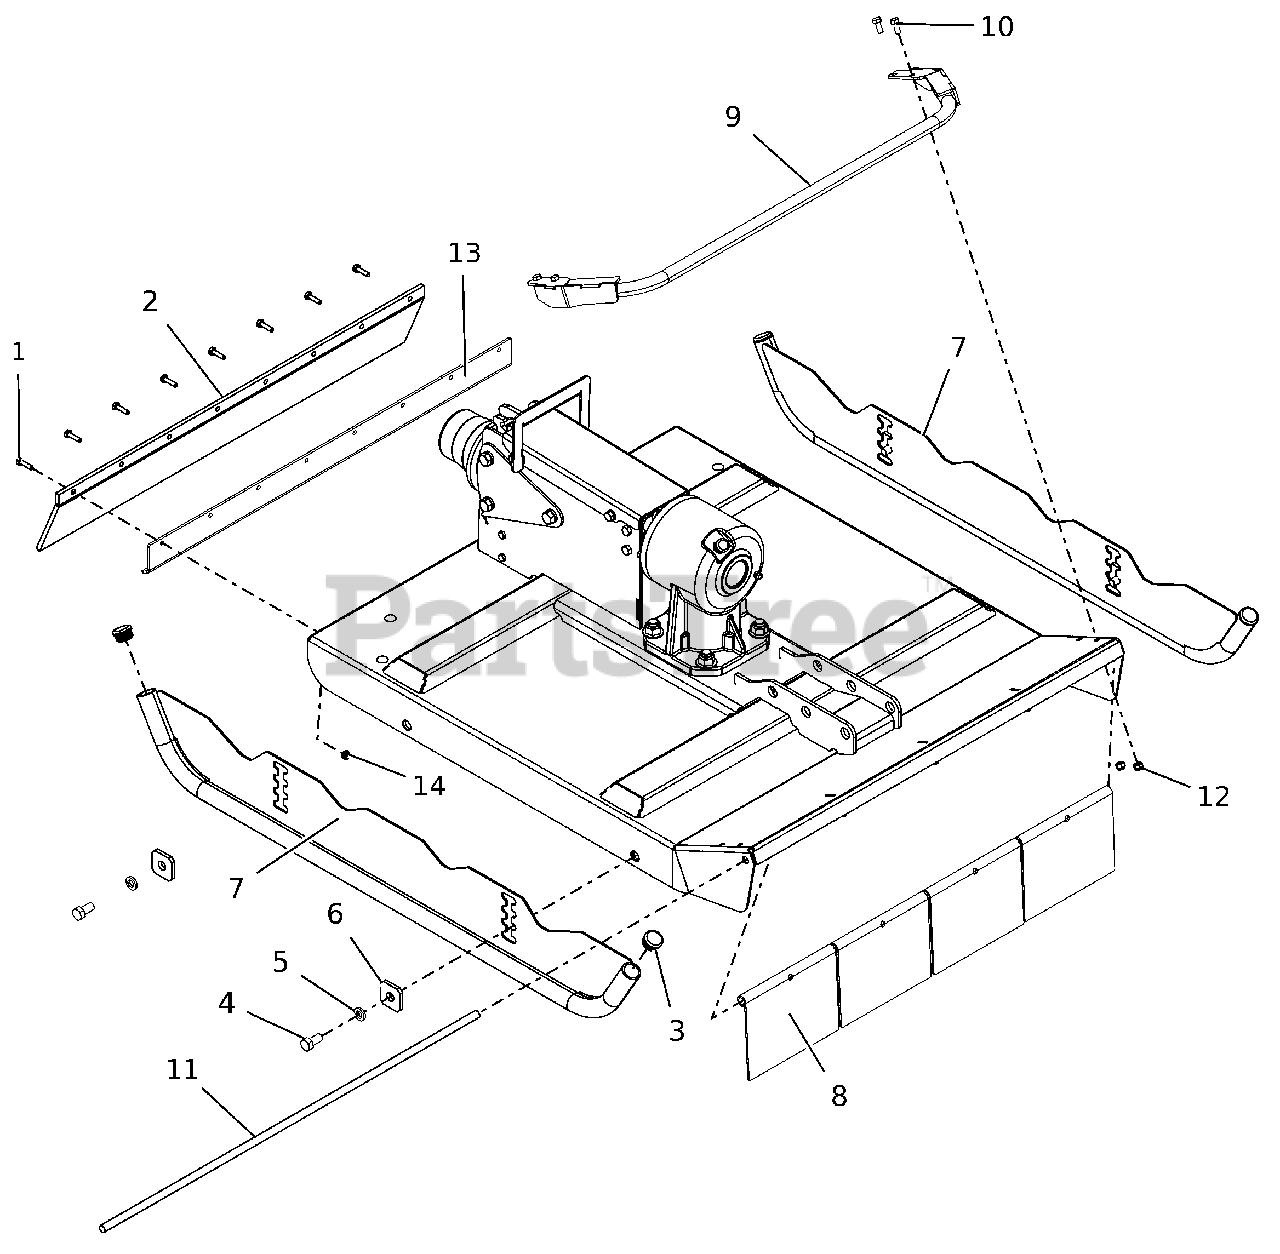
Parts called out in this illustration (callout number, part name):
1	BLT,HEX .25-20X1.00 G5 ZCC
2	SHEET, RUBBER
3	PLUG, CAP 1-1/4-10-14
4	BLT, HEX .50-13X1.00 G5 ZCC
5	WSHR,LK-HVY .500X.151 ZCC
6	WSHR-FLT .640X1.75X.250
7	WLDMT, SKID
8	PLATE, SKIRT FRONT RC
9	WLDMT, GUARD FRONT
10	BLT,HEX .31-18X.75 G5 ZCC
12	NUT,NYL .31-18 G5 ZCC
13	PLATE, REAR SKIRT MNT
14	NUT,NYL-FLG .25-20 GF ZCC
